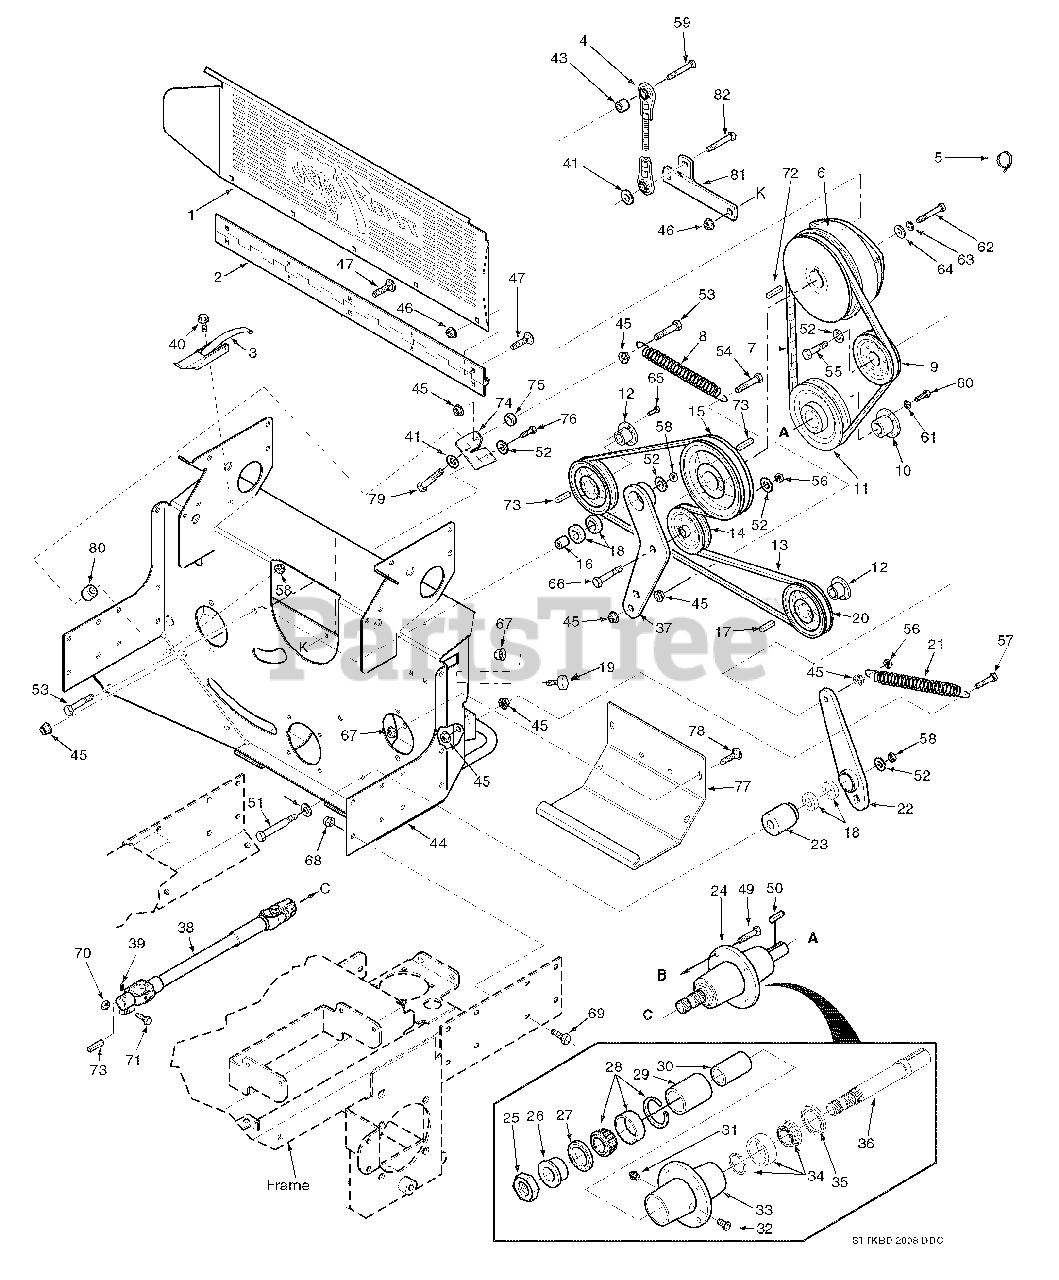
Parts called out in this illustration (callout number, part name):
1	Belt Guard, Rear
2	Hinge, Belt Guard
3	Latch, Hood
4	Rod Assembly, Clutch Anti-Rotation
5	Clamp, Cable
6	Clutch, Ogura GT-3.5
7	Belt, Deck Drive
8	Spring, Transmission Idler
9	Pulley, Idler 5" Dia.
10	Tapered Hub, 1" Bore
11	Pulley, 6.35 Tapered Bore
12	Tapered Hub, 17mm Bore
13	Belt, Pump Drive
14	Pulley, Idler 4" Dia.
15	Pulley, 5.35 Dia.-1.125 Bore
16	Spacer, Idler Bearing
17	Key, 5.0 x 5.0 x 25mm
18	Ball Bearing
19	Bumper, Rubber
20	Pulley,6.35" OD Tapered Bore
21	Spring, PTO
22	Idler Arm Weldment, PTO Drive
23	Pivot, Idler PTO
24	Spindle Assembly, Deck Drive
25	Nut, 1.06-18 Thread
26	Spindle Bushing, Bottom
27	Seal, 2.0 OD x 1.625 Bore
28	Roller Bearing Tapered
29	Spacer, Outside
30	Spacer, Inside
31	Grease Fitting, 1/4-28
32	Relief Fitting
33	Spindle Housing
34	Roller Bearing Tapered
35	Seal, 2.0 OD x 1.5 Bore
36	Shaft, Deck Drive
37	Idler Arm Weldment, Pump Drive
38	Driveshaft
39	Set Screw, 3/8-16 x 3/4" Torx Socket
40	Screw, #10-32 x .56
41	Flatwasher, 3/8-.391 x .938 x .105
42	Pin, Rue Cotter 3/8 Dia.
43	Spacer
44	Pump Mounting Plate Weldment
45	Nut, Serrated Flange 3/8-16
46	Nut, Serrated Flange 1/4-20
47	Bolt, Carriage 1/4-20 x 1/2"
48	Nut, Elastic Stop 5/16-18 Grade 8
49	Bolt, Hex Head 5/16-18 x 1-3/4" Grade 8
50	Key, 1/4 x 1/4 x 1-1/2"
51	Bolt, Hex Head 3/8-16 x 4-1/2" Grade 8 Black
52	Washer, 3/8" Hardened
53	Bolt, Hex Head 3/8-16 x 1-3/4" Grade 8 Black
54	Bolt, Hex Head 3/8-16 x 1-1/2" Grade 8 Black
55	Bolt, Hex Head 3/8-16 x 2-1/2" 1.5 Thread Grd.8
56	Nut, Center Lock 3/8-16
57	Bolt, Hex Head 3/8-16 x 1-1/2" Grade 8 Black
58	Nut, Elastic Stop 3/8-16
59	Bolt, Hex Head 3/8-16 x 2"
60	Bolt, Hex Head 1/4-20 x 1-3/8"
61	Lockwasher, 1/4" Spring
62	Bolt, Hex Head 7/16-20 x 2-1/2" UNF
63	Lockwasher, 7/16" Spring
64	Flatwasher, 7/16-.469 x 1.75 x .25
65	Bolt, Hex Head 1/4-20 x 1" Grade 8
66	Bolt, Hex Head 3/8-16 x 1-3/4"
67	Nut, Serrated Flange 5/16-18
68	Nut, Elastic Stop 3/8-16
69	Bolt, Hex Head 3/8-16 x 1"
70	Nut, Center Lock 3/8-16
71	Bolt, Hex Head 3/8-16 x 1-3/4"
72	Key, 1/4 x 1/4 x 2-1/4"
73	Key, 1/4 x 1/4 x 1"
74	Bracket
75	Spacer
76	Bolt, Hex Head 3/8-16 x 1"
77	Cover, Rear
78	Bolt, Carriage 5/16-18 x 3/4"
79	Bolt, Hex Head 3/8-16 x 2"
80	Spacer
81	Anchor Bracket, Anti-Rotation
82	Bolt, Hex Head 5/16-18 x 1-1/4"
